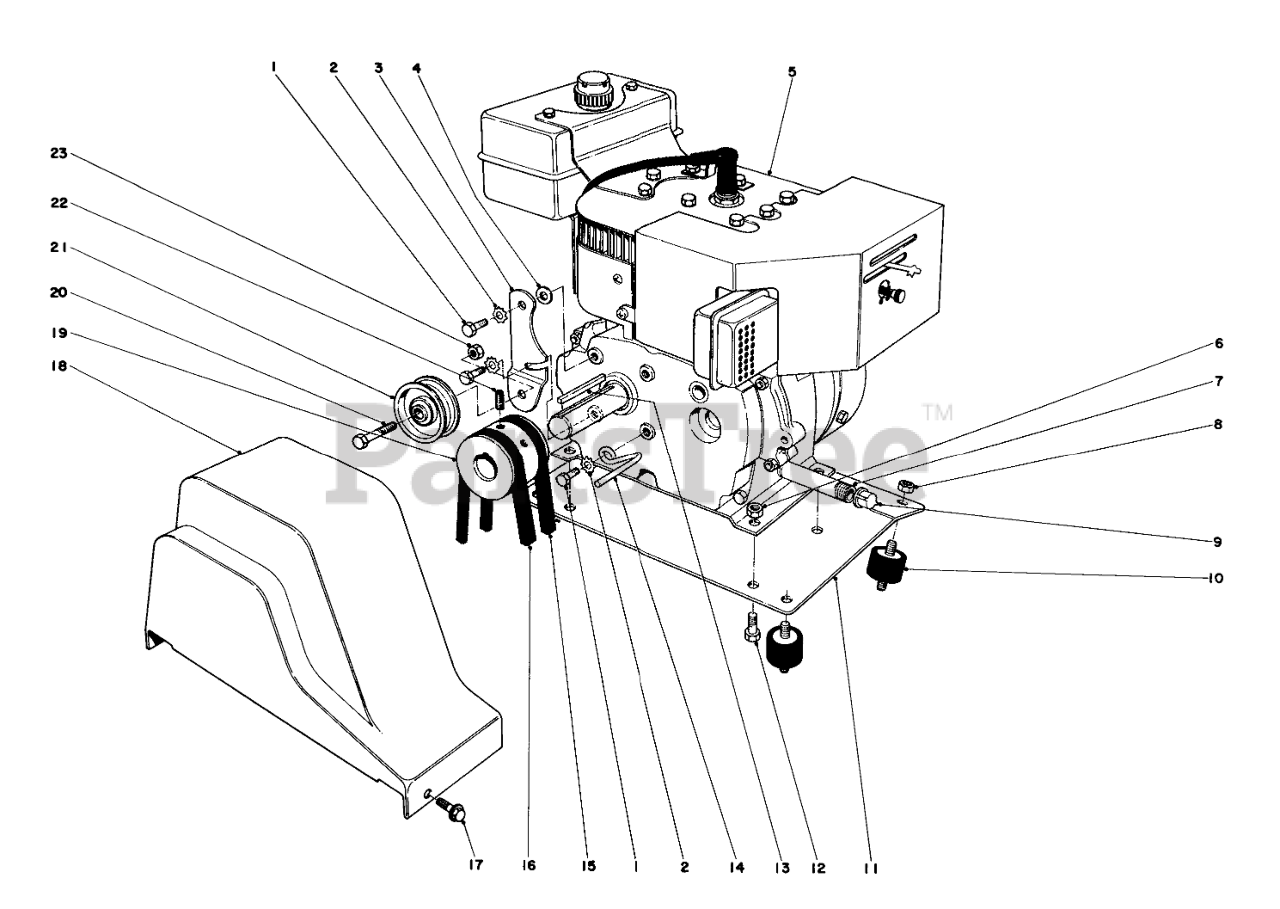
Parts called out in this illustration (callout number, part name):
1	SCREW-HH
2	WASHER-LOCK
3	ENGINE IDLER ARM
4	WASHER-PLAIN
5	Engine
6	NUT-LOCK, CONE
7	NIPPLE-PIPE
8	NUT-KEPS
9	CAP-PIPE
10	Engine Mount
11	Engine Mounting Plate
12	SCREW-HH
14	BELT RETAINER
15	V-BELT
16	V-Belt
17	SCREW-HWH
18	BELT GUARD
19	ENGINE PULLEY
20	SCREW-HH
21	PULLEY-IDLER
22	Screw-Set
23	NUT-HEX
